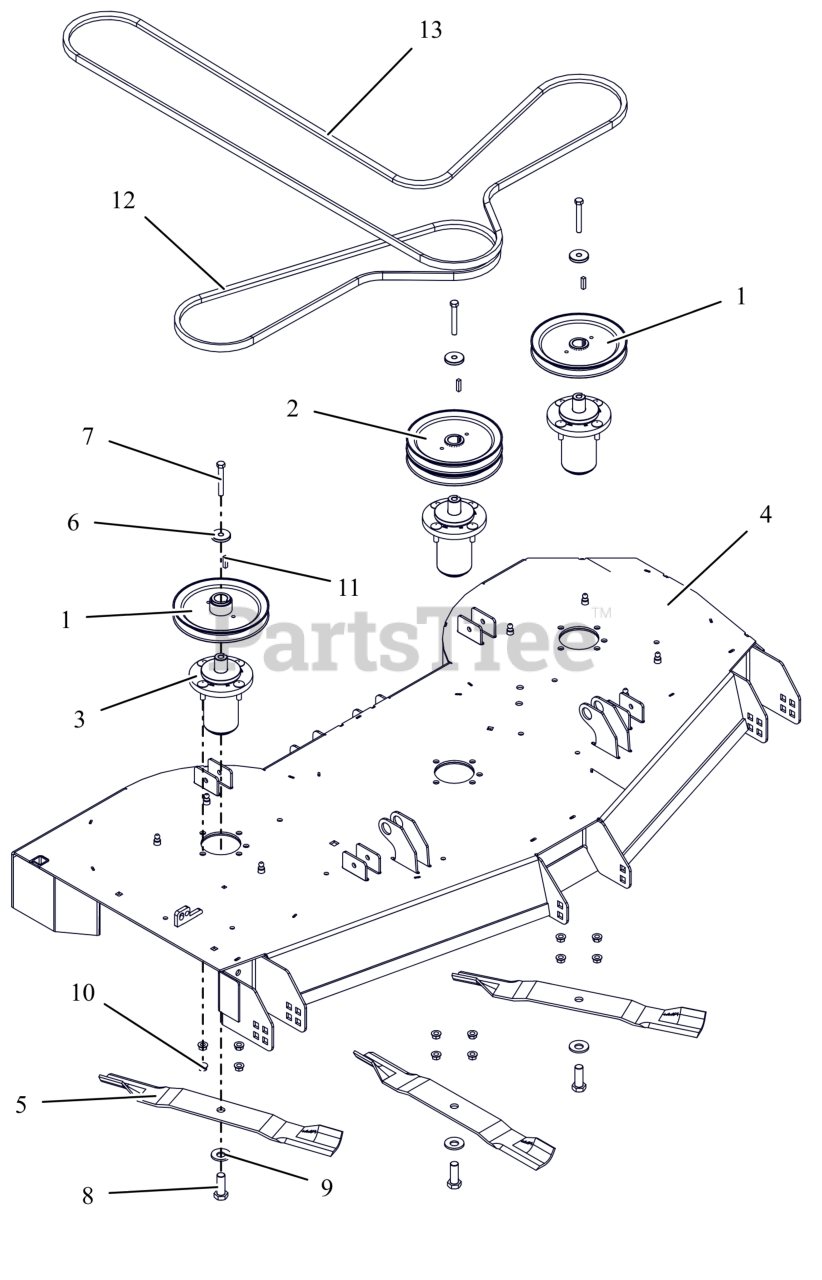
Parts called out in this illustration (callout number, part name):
1	PULLEY, V-7.50 OD X 1"ID
2	PULLEY, DOUBLE 1"X7.50"&7.50" (BLACK)
3	ASM, MAINT FREE ALUM SPINDLE
4	KIT, DECK-60 W/DECALS 7GA XF3 RED
5	BLADE, 20.5"
6	RETAINER, SHEAVE
7	BLT, HEX .38-16X2.75 G8 ZCC
8	BLT, HEX .62-18X1.75 G8 ZCC
9	WSHR-BLVL .669X1.535X.138
10	NUT-LK-CTR-FLG .375-16 GF ZCC
11	KEY, SQ .25X.25X1.00 RC 40-50
12	V-BELT, B-COGGED
13	V-BELT, HB SECTION
